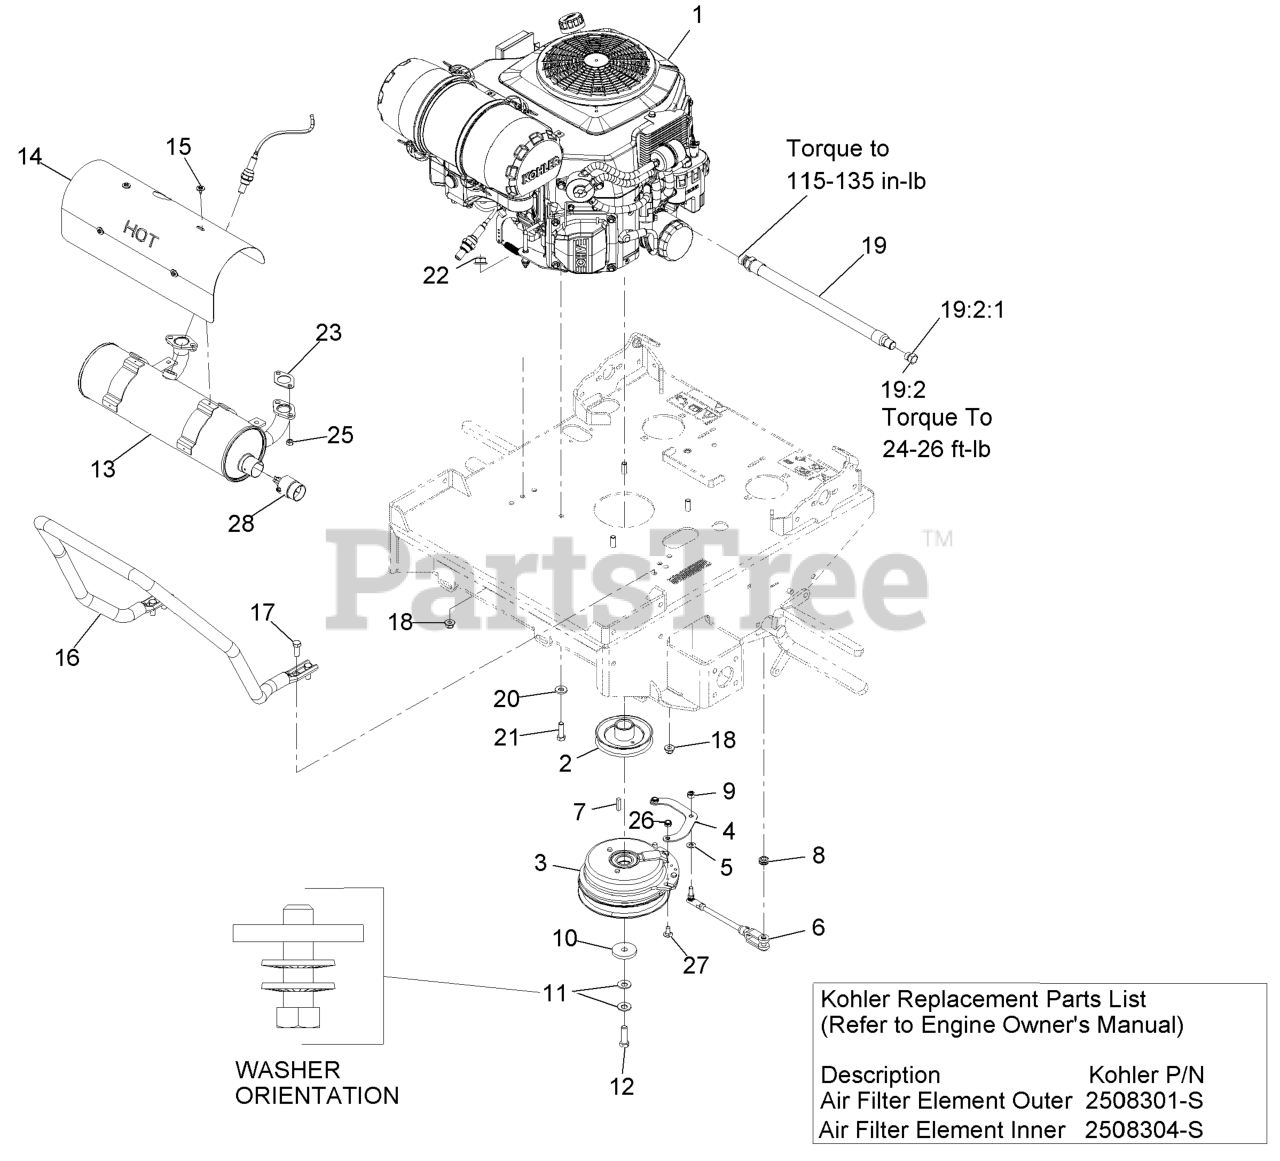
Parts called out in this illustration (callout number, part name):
2	SHEAVE W/ HUB
3	CLUTCH, 200 FT/LBS, 1.13
4	STRAP, CLUTCH
5	WASHER-PLAIN
6	ASM, CLUTCH ANCHOR
7	KEY
8	GROMMET
9	NUT-LOCK
10	WASHER-CLUTCH
11	WASHER-SPRING
12	BOLT-HEX, TAP
13	MUFFLER-TTX, EFI
14	SHIELD-MUFFLER,TTX EFI
15	SCREW-HH, THREAD FORMING
16	GUARD,AIR CLEANER
17	SCREW-HH
18	NUT-HF, NI
19	OIL DRAIN HOSE ASM
19:2	PLUG-HH
19:2:1	O-RING
20	Washer-Spring Disc 5/16
21	SCREW-HH
22	NUT-HF, NI
23	GASKET-EXHAUST
26	NUT-LOCK, NI
27	SCREW-CARR
28	ARRESTOR,SPARK 1.375 DIA
